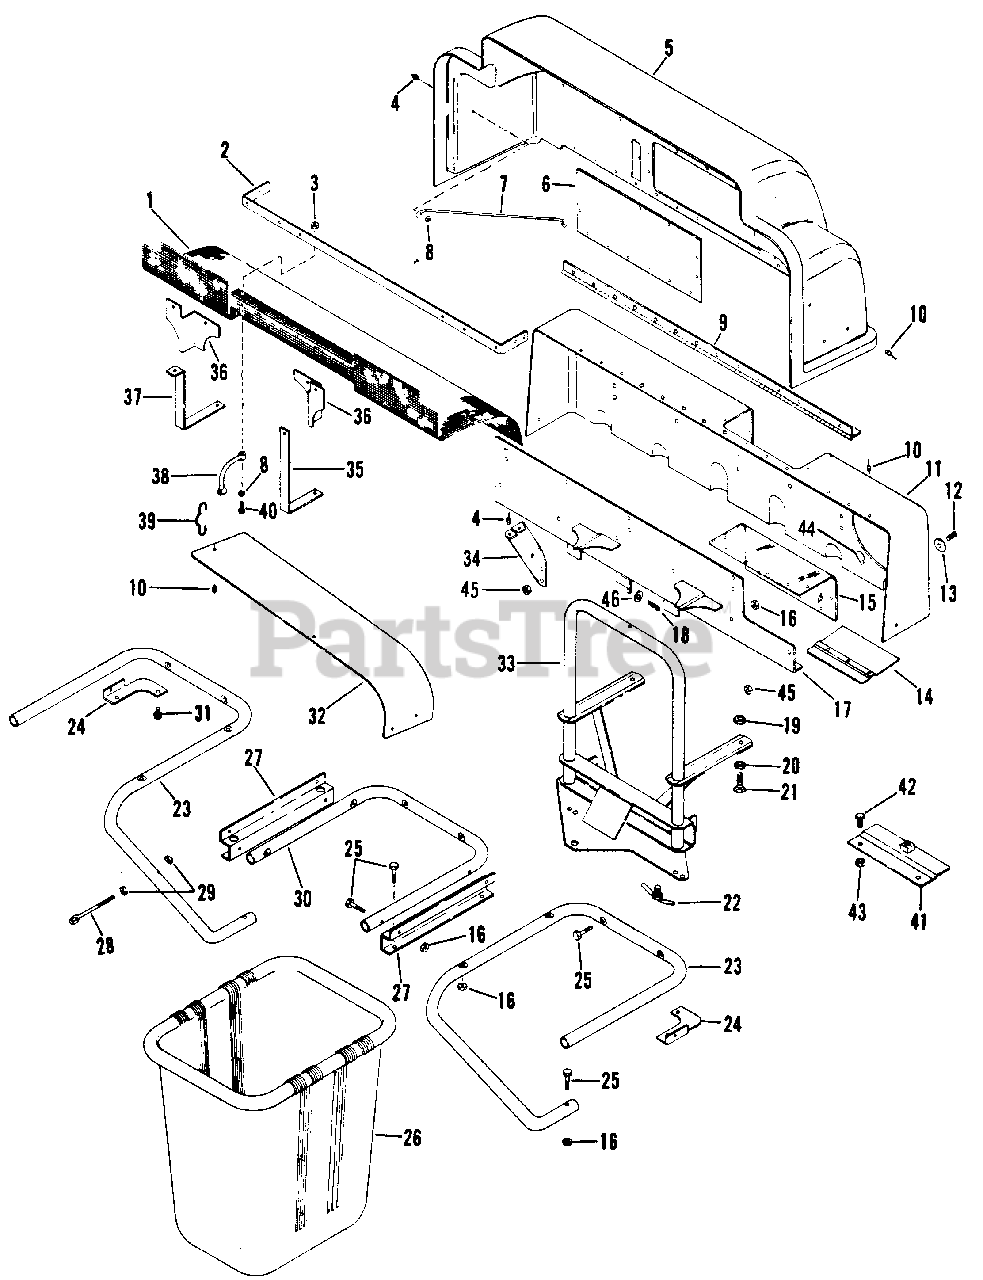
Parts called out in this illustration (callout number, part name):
1	Screen
2	Bracket, Screen Mounting
3	Nut, Lock 10-24
4	Rivet, Pop-Domed
5	Cover, Hinged
6	Window, Hinged Cover
7	Brace
8	Washer, Flat .188x.562x.049
10	Rivet, Pop-Domed
11	Cover, Stationary
12	Bolt, Hex 5/16-18x.875
13	Washer, Flat .340x1.12x.063
14	Guide, Tube
15	Window, Stationary Cover
16	Nut, Lock 5/16-18
17	Bracket, Mounting
18	Hairpin, Internal
19	Nut, Lock 3/8-16
20	Nut, Hex 3/8-16
21	Bolt, Hex 3/8-16x1.25
22	Bolt, T-Handle
23	Tube, Right
23	Tube, Left
24	Bracket, R.H. Corner
24	Bracket, L.H. Corner
25	Screw, Machine 5/16-18x1.50
26	Basket, Grass Bagger
27	Bracket, Tube
28	Eyebolt
29	Nut, Lock 1/4-20
30	Tube, Center
31	Bolt, Hex 5/16-18x.50
33	Frame, Attachment
34	Brace
35	Brace
36	Baffle, L.H.
36	Baffle, R.H.
37	Brace
38	Strap
39	Hook
40	Screw, Mach. 10-24x1.00 Rd Hd
41	Weldment, Adaptor
42	Bolt, Hex 3/8-16x.75
43	Nut, Lock 3/8-16
44	Clip, Boot
45	Nut, Lock 5/16-18
46	Washer, Flat .375x.734x.065
NS	Decal, Gravely Logo
